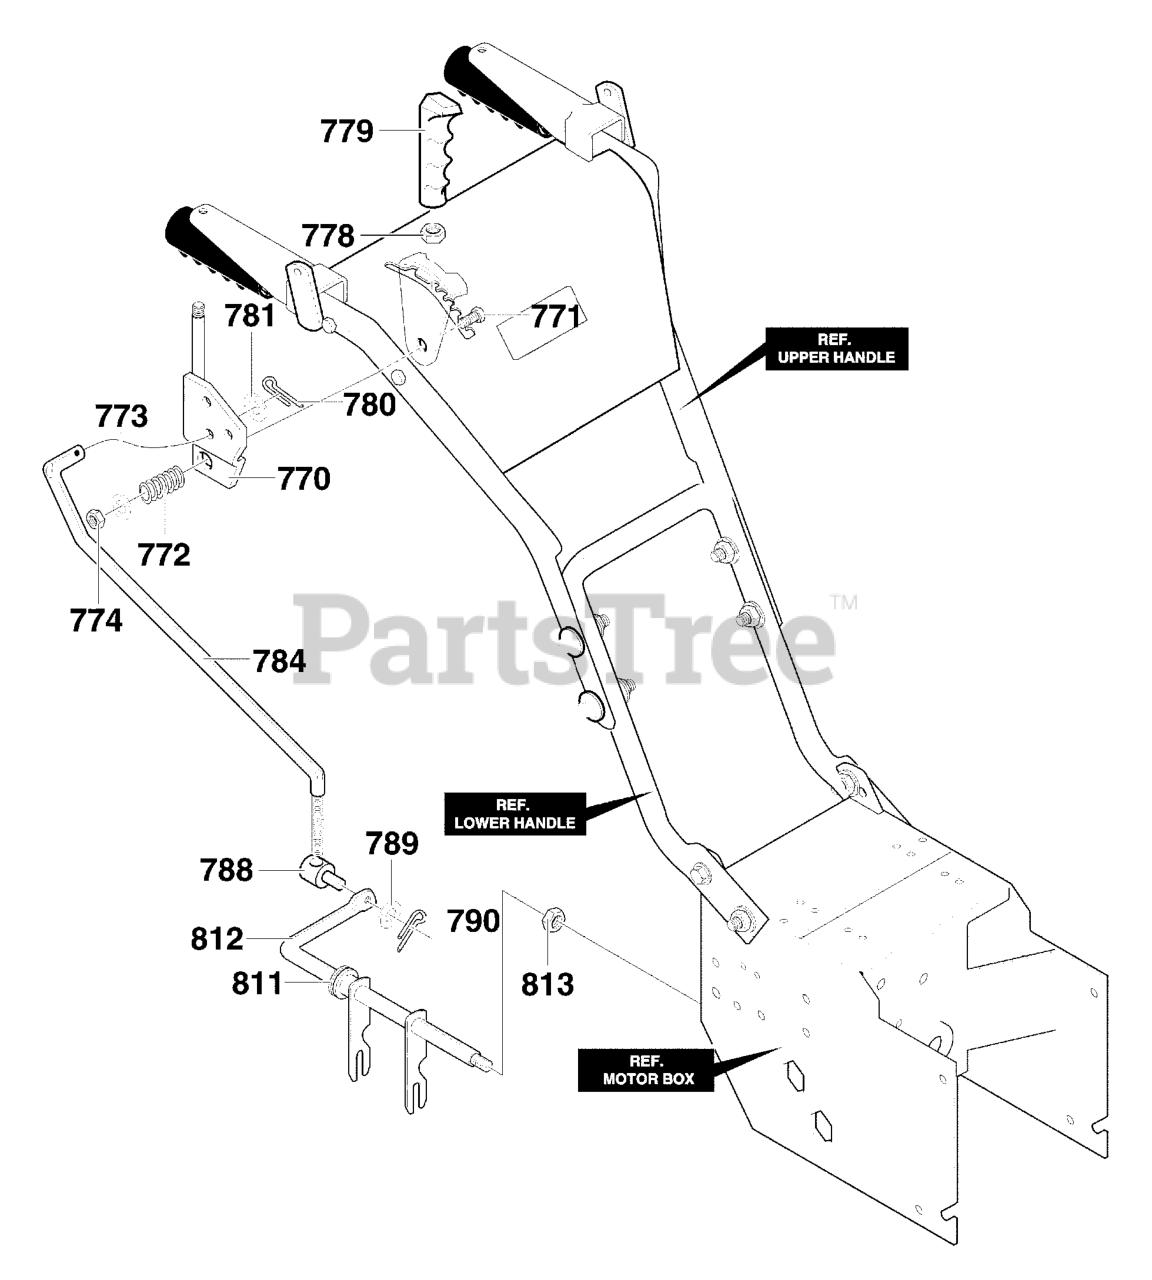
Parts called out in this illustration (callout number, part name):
770	HANDLE ASSY SPD CTRL
771	SCREW 3/8-16X2.00
772	SPRING
773	FLATWASHER
774	NUT, 3/8-16 HEXNYL
778	NUT, 3/8-16 REGHEX
779	HANDLE 3/8-16
780	PIN, COTTER
781	FLATWASHER
784	ROD, SPEED CONTROL
788	NUT, TRUNNION
789	FLATWASHER
790	COTTER PIN
811	BEARING, FLANGE
812	ROD, ASSY YOKE
813	NUT, 3/8-16 HXCTRLK
